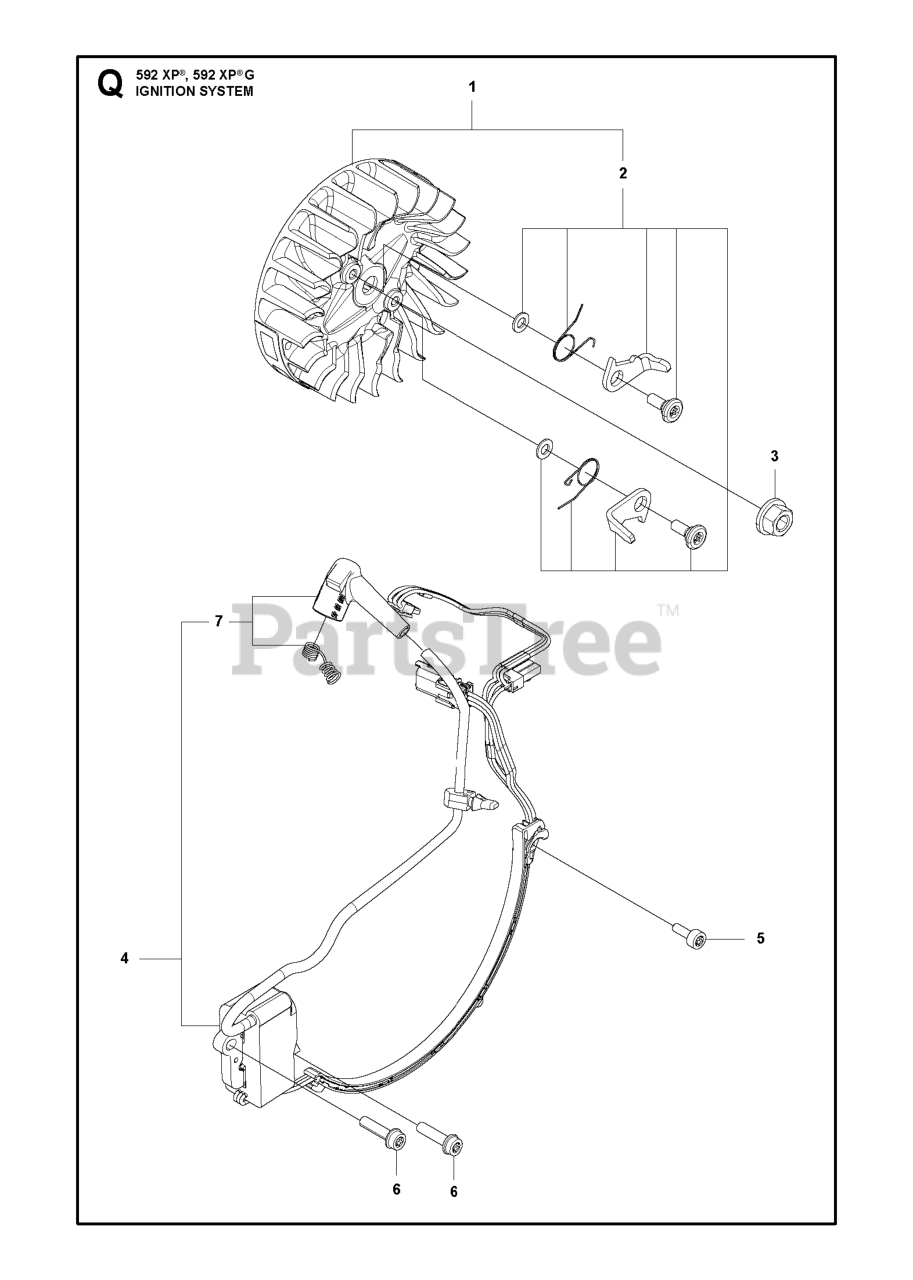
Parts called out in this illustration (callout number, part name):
1	FLYWHEEL ASSY D114
2	SCREW KIT PAWL 90CC SPARE PART
3	NUT W/ WASHER
4	IGNITION KIT
5	SCREW ITXSCM
7	SPARK PLUG CAP KIT SPARE PART
